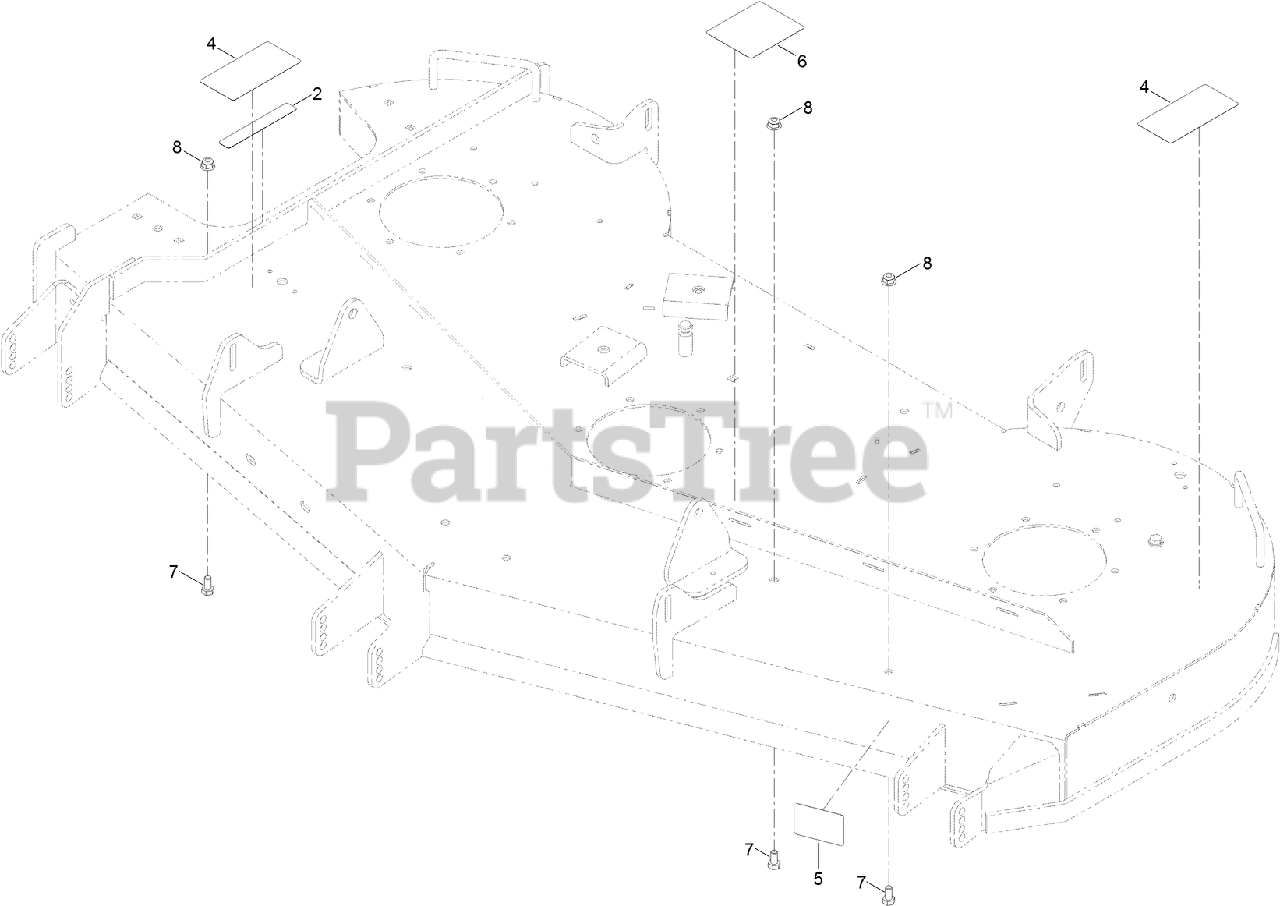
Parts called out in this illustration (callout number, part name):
2	DECAL-DANGER
4	DECAL-DANGER, DECK
5	DECAL-SCALP, ANTI
6	DECAL-ROUTING, BELT
7	SCREW-HH
8	NUT-HF, NI
